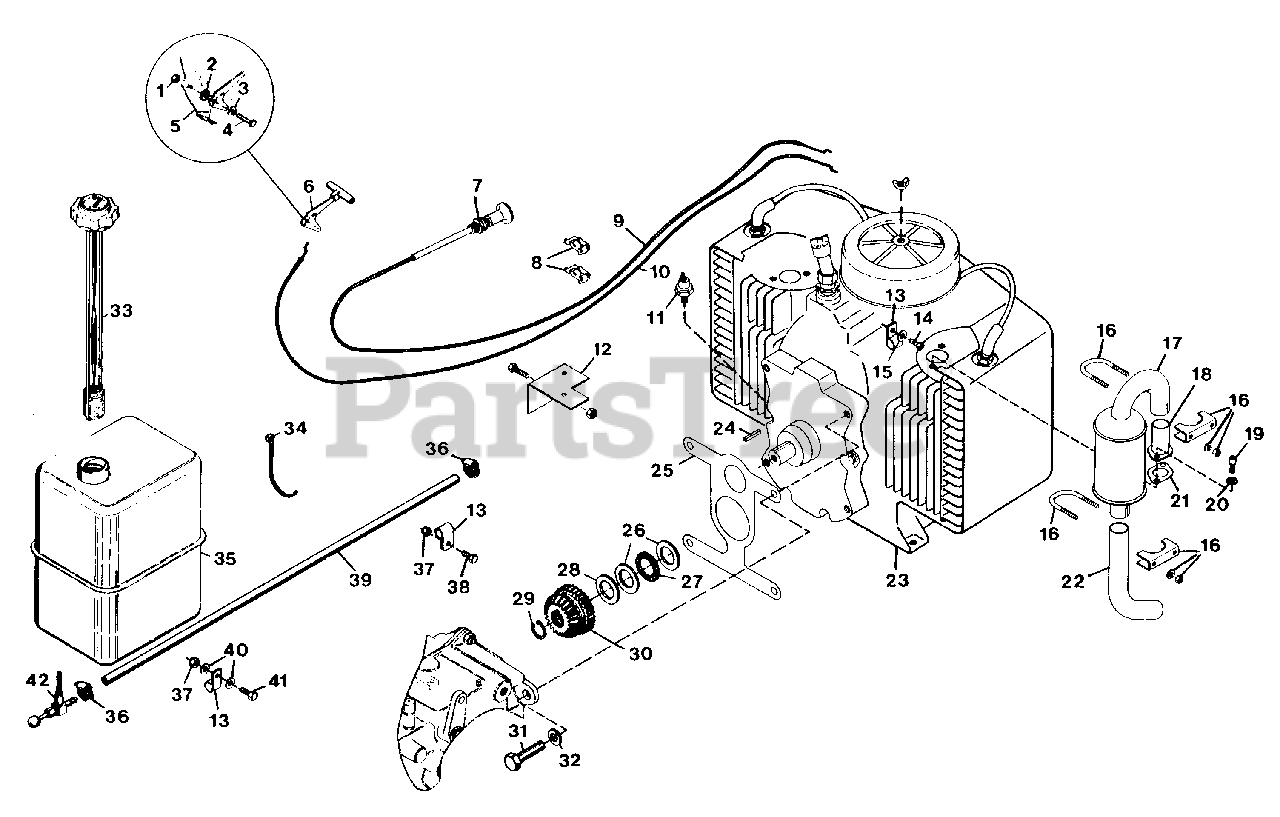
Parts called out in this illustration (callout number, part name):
1	NUT, LOCK 1/4-28
2	WASHER, FRICTION
3	WASHER, SPRING
4	BOLT, HEX 1/4-28X.75
5	BRACKET, MOUNTING
6	ASSEMBLY, KNOB AND LEVER
7	NUT, JAM 3/8-24 HEX
8	CLIP, SPEED
9	CONTROL, CHOKE
10	ASSEMBLY, CHOKE CONDUIT
11	SWITCH, PRESSURE
12	BRACKET, THROTTLE AND CHOKE
13	CLAMP, NYLON
14	SCREW, TAPPING 1/4-20X.625 HST
15	WASHER, FLAT .281X.625X.065
16	CLAMP, MUFFLER
17	MUFFLER
18	WELDMENT, HEADER
19	SCREW, CAP 5/16-18X.75 S/HD
20	WASHER, LOCK 5/16-18 REG.
21	GASKET, EXHAUST
22	EXTENSION, EXHAUST
23	ENGINE, 16 HP MAGNUM
24	KEY, SQUARE .250X1.250
25	GASKET, ENGINE TO TRANSMISSION
26	RACE, BRG 1.125X1.750X.123/.126
27	BEARING, THRUST 1.127X1.740X.078
28	SHIM, 1.125X1.750X.030
29	RING, RETAINING 1.125 SHAFT
30	GEAR, SPUR AND BEVEL, INPUT
31	BOLT, HEX 1/2-13X1.75
32	WASHER, LOCK 1/2 REG.
33	GAUGE, GAS
34	TIE, CABLE
35	TANK, FUEL
36	CLAMP, HOSE
37	NUT, LOCK 5/16-18
38	BOLT, HEX 5/16-18X.75
39	LINE, FUEL
40	WASHER, FLAT .344X.688X.065
41	BOLT, HEX 5/16-18X1.00
42	VALVE, FUEL 90 DEG. REVERSE FLOW
NS	NUT, LOCK 10-32
NS	SCREW, MACHINE 10-32X.50 PHD
